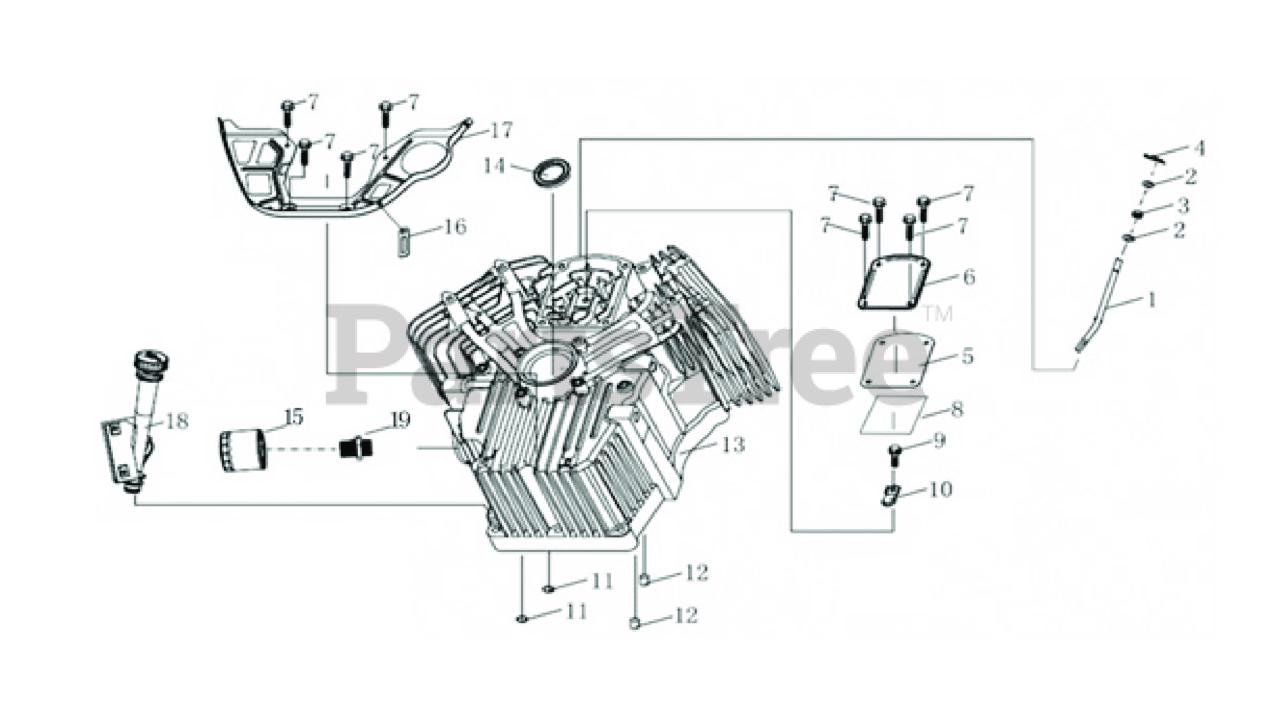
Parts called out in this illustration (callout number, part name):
1	Arm, Speed Regulating
2	Washer, Flat
3	Seal, Oil
4	Pin, Cotter
5	Bushing, oil lube - 3/4 ID x 1.0
6	Bushing, Bronze Oilite - 3/4 ID
7	Bolt, Flange
8	Block, Filter
9	Bolt, Flange
10	Valve, Leaf
12	Pin, Location
13	Crankcase Body, SR708
14	Seal, Oil
15	Filter, Oil
16	Bolt, Oil Filter Mounting
17	Plate, Side
18	Bronze Bushing, 7/8 ID x 1.0 Flanged
